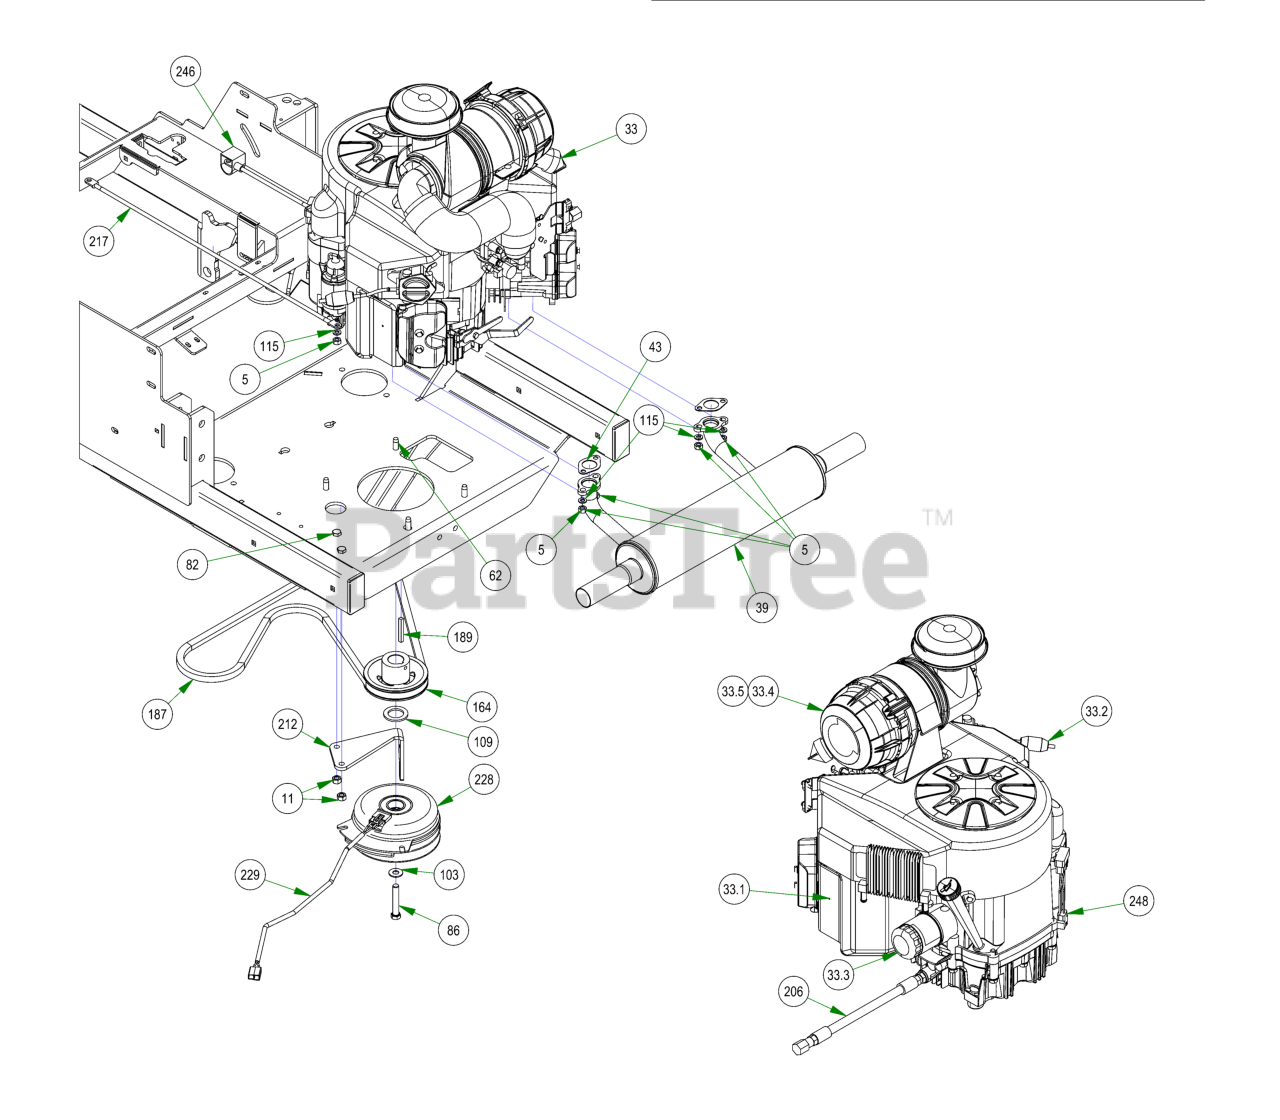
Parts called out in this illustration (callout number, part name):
5	M8-1.25 DIN 934 HEX NUT (CL.8) ZINC
11	3/8-16 HEX NUT ZINC
31	1 1/2 x 3 Frame Plug
33	Kawasaki FX850 Engine
33.1	Spark Plug - Kawasaki
33.2	Universal Inline Fuel Filter
33.3	Oil Filter
33.4	Canister Air Filter- Outer
33.5	Canister Air Filter- Inner
39	2019 Rebel/Rogue Kawasaki 850 Muffler
43	Exhaust Gasket
62	3/8-16 X 1-1/8HEX WASHER UNSLOT SERRATED
82	3/8-16 X 1-1/4 HEX CAP SCREW (GR.5) ZINC
86	7/16-20 X 2-1/2 HEX Bolt GR 8 W/ Patch
103	3/8 FLAT WASHER USS (1" OD) ZINC
109	1.140 ID X 1.750 OD X .132 THICK FLAT WASHER PLAIN
115	5/16 SPLIT LOCKWASHER ZINC
164	4 3/4 Motor Pulley
187	2019 Rogue Pump Belt 68"
189	1/4 X 2 SQ MACHINERY KEY 1018 STL PLAIN
206	Kawasaki Oil Drain
212	PTO Engager Holder
217	24" Red Battery Cable
228	Clutch Assembly
229	Clutch Pigtail
230	2021 Rogue Suspension Frame Painted
246	Starter Cable
248	2019 Harness Adaptor-Gen2 FX-ALL
